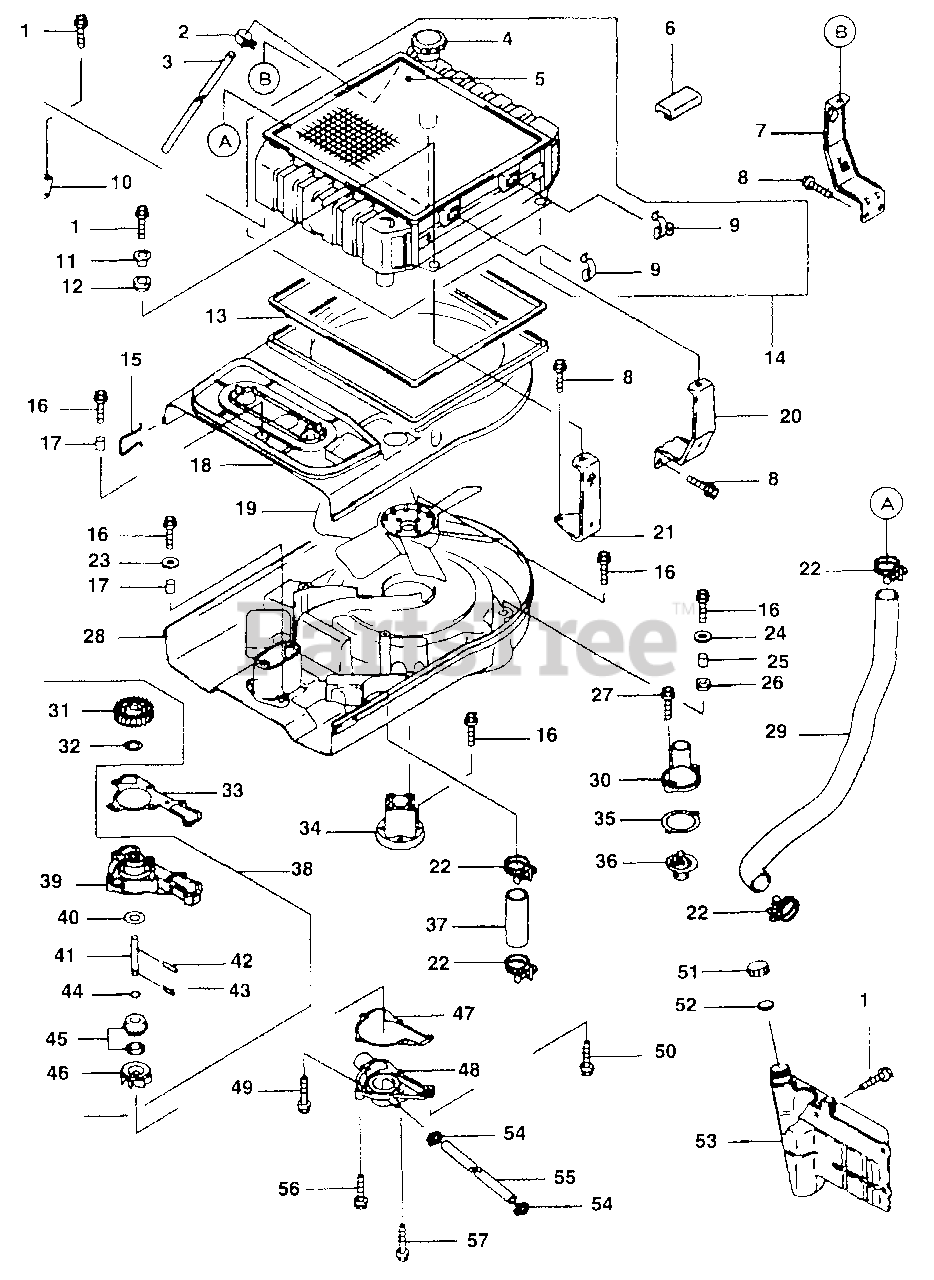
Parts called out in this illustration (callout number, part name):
1	Flanged Bolt
4	Pressure Cap Ass'y
7	Bracket
8	Flanged Bolt
14	Radiator Ass'y
16	Flanged Bolt
21	Bracket
33	Pump Case Gasket
35	Thermostat Cover Gasket
36	Thermostat
38	Water Pump
41	Impeller Shaft
45	Mechanical Seal
47	Pump Cover Gasket
48	Pump Cover
49	Flanged Bolt
50	Flanged Bolt
56	Flanged Bolt
57	Flanged Bolt
